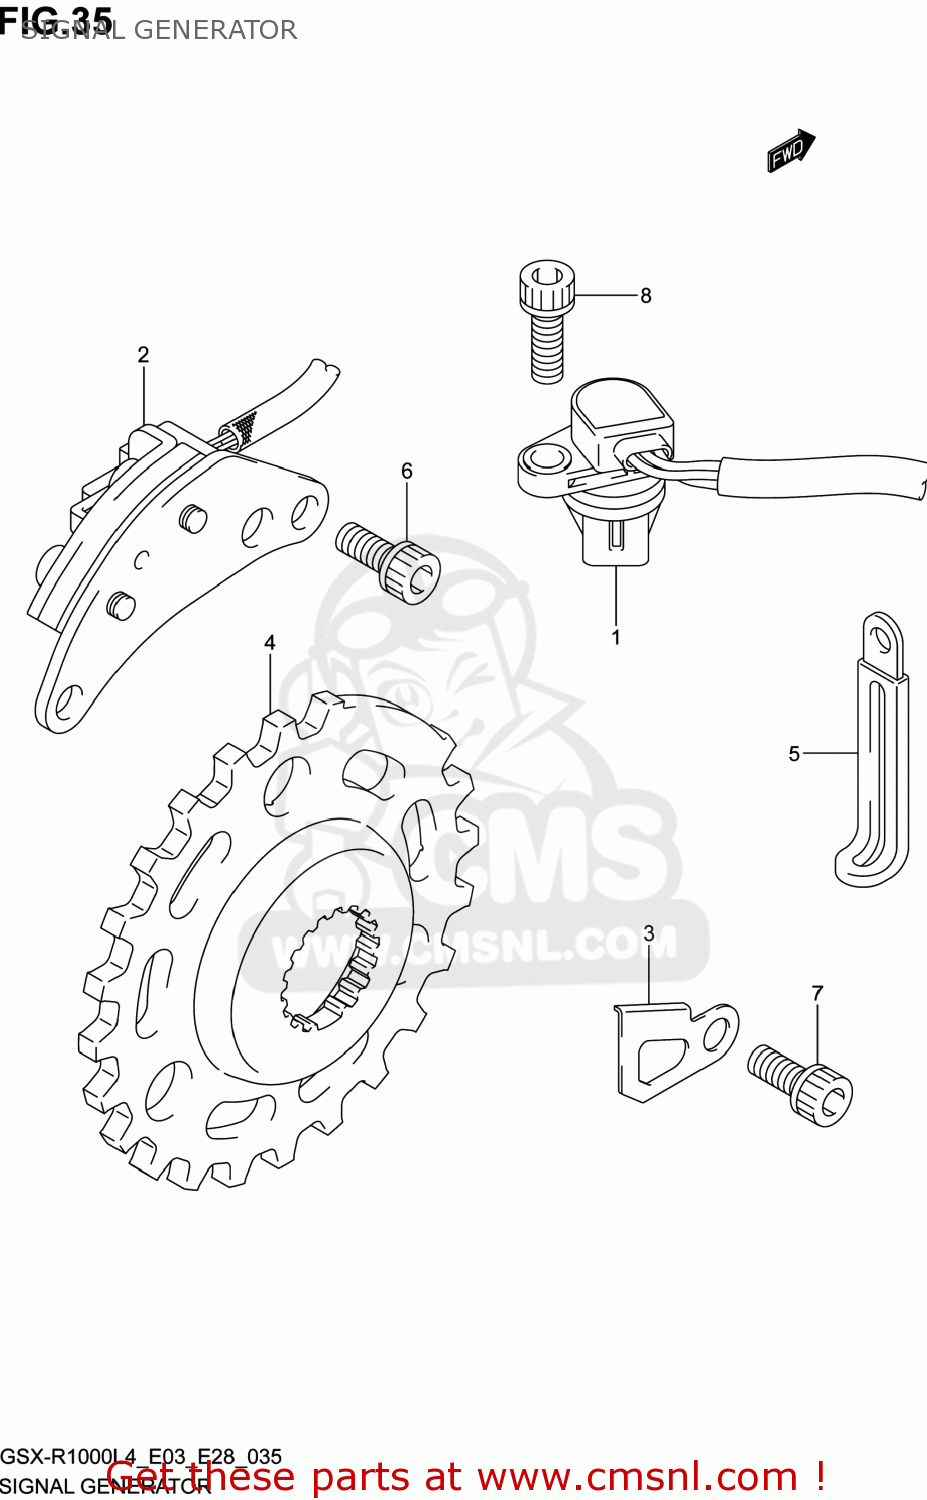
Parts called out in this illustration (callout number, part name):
1	SENSOR ASSY,CAM POSITION
2	STARTER,SIGNAL GENERATOR
3	CLAMP,SIGNAL GENERATORERATOR
4	ROTOR,SIGNAL GENERATOR
5	CLAMP(L:45)
6	BOLT
7	BOLT
8	BOLT
